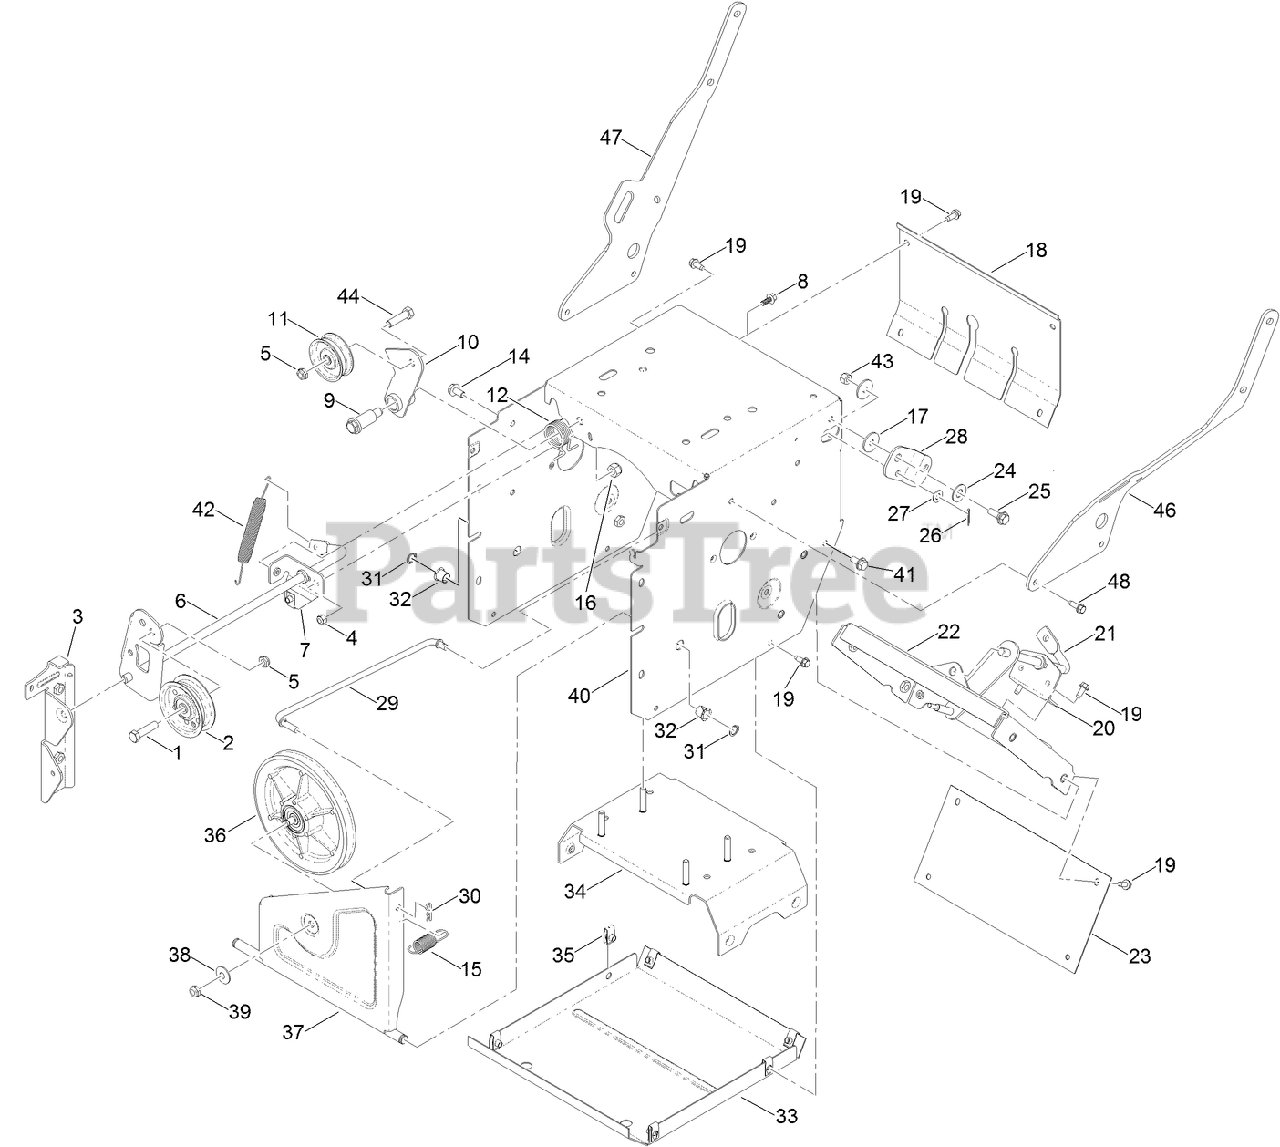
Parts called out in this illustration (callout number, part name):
1	SCREW-HH
2	PULLEY-IDLER
3	BRACKET-IDLER, IMPELLER
4	NUT-LOCK, NI
5	NUT-LOCK, NI
6	IMPELLER CLUTCH ASM
7	BRACKET-CLUTCH, IMPELLER
8	SCREW-HHF
9	BOLT-SHOULDER
10	ARM-IDLER, TRACTION
11	PULLEY-IDLER
12	SPRING-TORSION
14	SCREW-HHF
15	SPRING-EXTENSION
16	NUT-LOCK, NI
17	WASHER-PIVOT
18	COVER-UPPER
19	SCREW-HWH
20	BRACKET-ROD, SHIFT
21	LEVER-CONTROL, TRACTION
22	SHIFT PLATE ASM
23	COVER-LOWER
24	WASHER
25	SCREW-SHOULDER
26	PIN-COTTER
27	WASHER-PLAIN
28	BELLCRANK-DRIVE
29	LINK-CONTROL, SPEED
30	PIN-COTTER
31	RING-RETAINING
32	BUSHING-NYLINER
33	PAN-BOTTOM
34	BRACE-FRAME
36	PULLEY-TRACTION
37	BRACKET-WHEEL, FRICTION
38	WASHER-BELLEVILLE
39	NUT-HEX
40	FRAME-TRACTION
41	SCREW-HWHTF
42	SPRING-EXTENSION
43	NUT-LOCK, NI
44	SCREW-HH
46	BRACE-HANDLE, LH
47	BRACE-HANDLE, RH
48	SCREW-HWH, THREAD ROLL
